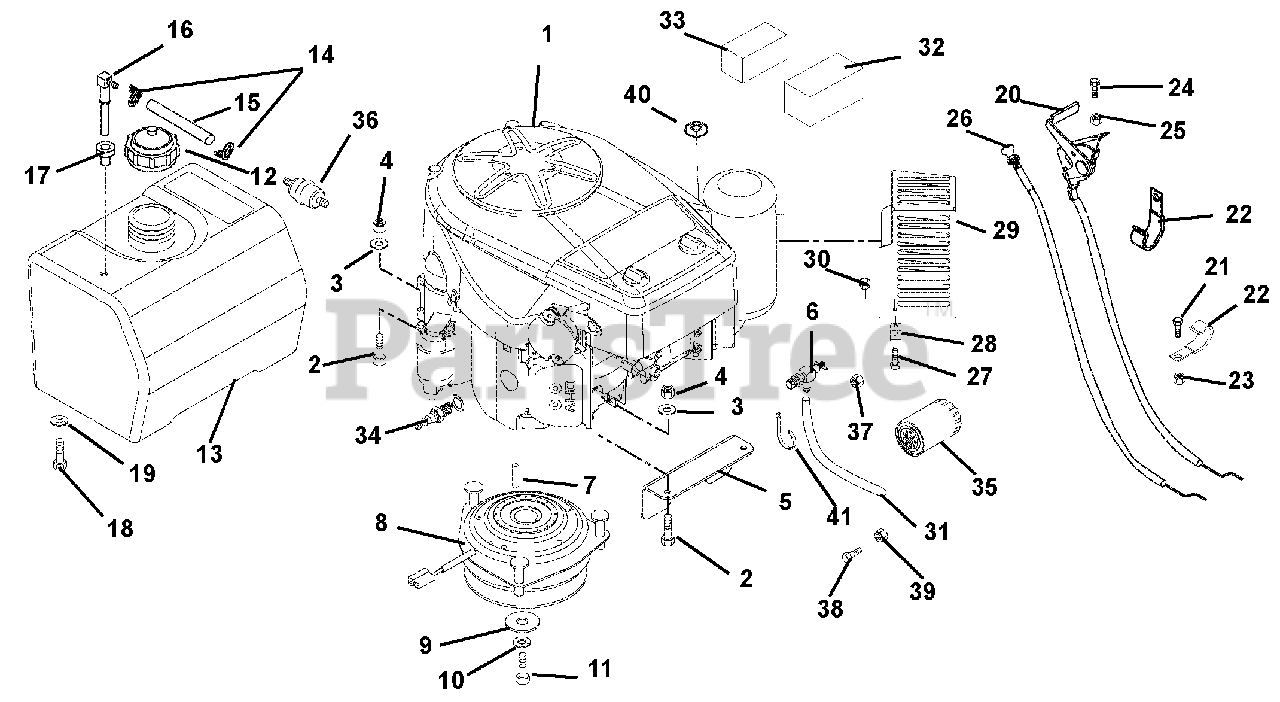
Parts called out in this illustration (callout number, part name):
1	Engine, 15 HP Kawasaki (106, 116,120, 314)
2	Bolt-Hex .31-18 x 1.75 Grade 5
3	Washer-Locking .31 x .078 Regular
4	Nut-Hex .31-18
5	Bracket, Clutch
6	Valve, Oil Drain
7	Key-Square .25 x 1.25 x 25 SAE 8630 OR SAE 1035
8	Clutch, Electric
9	Washer-Flat-Steel .469 x 2.00 x .25
10	Washer-Locking .44 x .109 Regular
11	Bolt-Hex .44-20 x 3.00 Grade 5
12	Cap, Fuel
13	Tank, Fuel
14	Clamp-Hose Wire .49/.51 x .116
15	Gas Line-Bulk .25 I.D.
16	Fitting, Tank
17	Bushing
18	Bolt-Hex .38-16 x .75 Grade 5
19	Washer-Locking .38 x .094 Regular
20	Cable, Throttle-with Liner (106, 108, 109)
21	Bolt-Hex .31-18 x .75 Grade 5
22	J-Clamp
23	Nut-Locking-Nylon .312-18
24	Screw-Machine 10-24 x .75 Hex Washer Head
25	Nut-Locking-Nylon 10-24 with Insert
26	Control, Choke
27	Bolt-Hex .31-18 x .75 Grade 5 (314)
28	Bracket, Muffler Guard (314)
29	Guard, Muffler (314)
30	Nut-Locking-Center .31-18 (314)
31	Tube, Oil Drain
32	Filter, Air Paper (106, 116, 120, 314)
33	Filter, Air Foam (106, 116, 120, 314)
34	Spark Plug
35	Filter, Oil
36	Fuel Filter- Kawasaki
37	Nut-Locking-Center .31-18 (314)
38	Bolt-Hex .38-16 x .75 Grade 5 (314)
39	Nut-Locking-Center .38-16 (314)
40	Washer-Flat-Steel .38 x .87 x .179 (314)
41	Cable Tie
